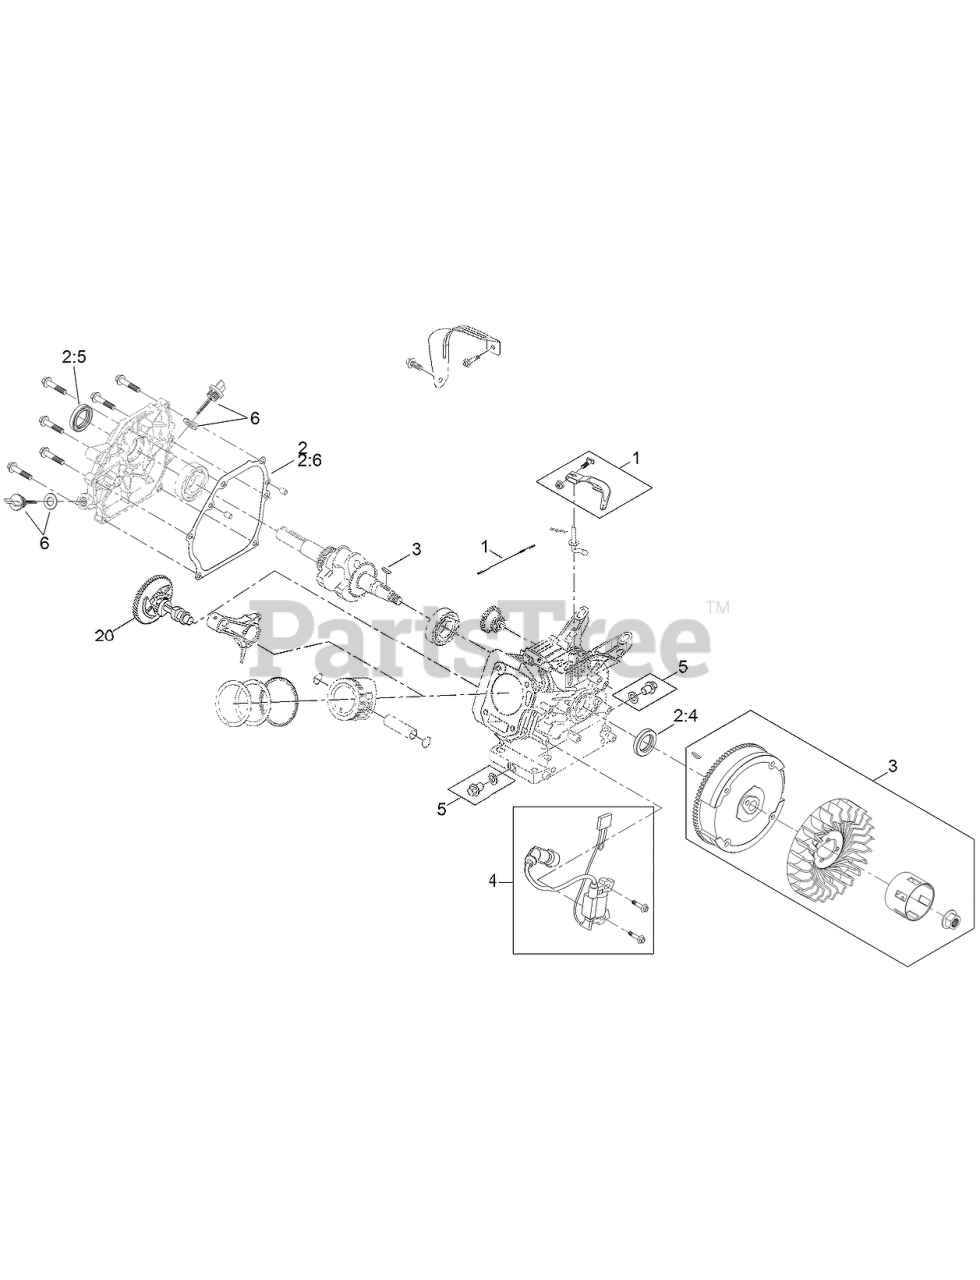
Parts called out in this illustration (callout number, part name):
1	GOVERNOR KIT
2	GASKET AND SEAL KIT
2:4	Seal-Oil
2:5	Seal-Oil
2:6	GASKET-COVER, CRANKCASE
3	RECOIL FLYWHEEL KIT
4	IGNITION KIT
5	DRAIN PLUG KIT
6	DIPSTICK AND O-RING KIT
20	CAMSHAFT
